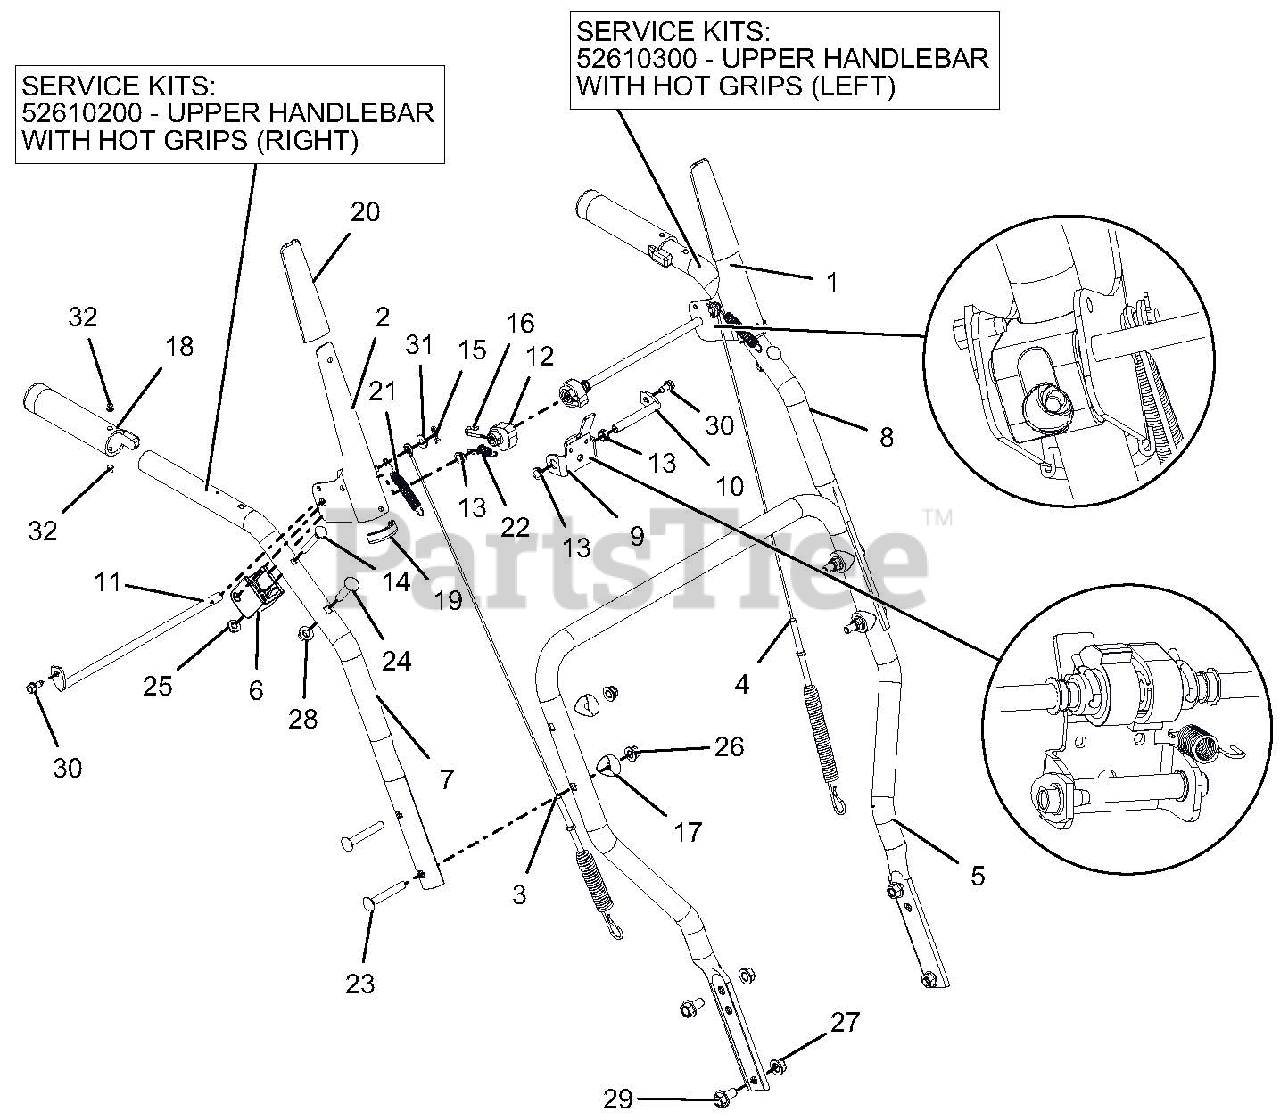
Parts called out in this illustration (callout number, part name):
1	LEVER, CLUTCH-LH
2	LEVER, CLUTCH-RH
3	CABLE, AUGER (DELUXE & PRO)
4	CABLE, UPPER TRACTION
5	HANDLEBAR, LOWER
6	BLOCK, CLUTCH PADDLE
7	HANDLEBAR, UPPER - RH
7	HANDLEBAR, UPPER RH W/HW
8	HANDLEBAR, UPPER - LH
8	HANDLEBAR, UPPER LH W/HW
9	BRACKET, INTERLOCK ARM
10	ROD, PIVOT - INTERLOCK
11	ROD, PADDLE MOUNT - PRO
12	CAM, INTERLOCK
13	BUSHING, POLYLINER-.38 SNAPIN
14	BLT-RDHDXLSQNK .25-20X2.0 G5YZ
15	PIN-HAIR INT .06X.18X.77
16	PIN, SPRING CLIP
17	SPACER, HANDLEBAR
18	HEATED GRIP, MAGURA
19	EDGING, CLUTCH PADDLE - 2.00"
20	CLUTCH PADDLE SLEEVE - GRAY
21	SPRING, EXTENSION
22	SPRING-EXT .047X.438X1.45
23	@BLT-RDHDSQNK .31-18X2.25 G5YZ
24	@BLT-RDHDSQNK .31-18X1.50 G5YZ
25	@NUT-LK-CTR-FLG .25-20 YWZC
26	@NUT-LK-NYL-FLG .31-18 YWZC
27	@NUT-LK-TOP-FLG .38-16 YWZC
28	@NUT-LK-TOP-FLG .31-18 YWZC
29	BLT-SERHFWH .38-16X.75 YWZC
30	SCR-TAP .25-20X.50 HWH TR YWZ
31	@WSHR-FL-STL.281X.62X.065 YWZC
32	RVT-POP #43 .125X.313 STL ZINC
